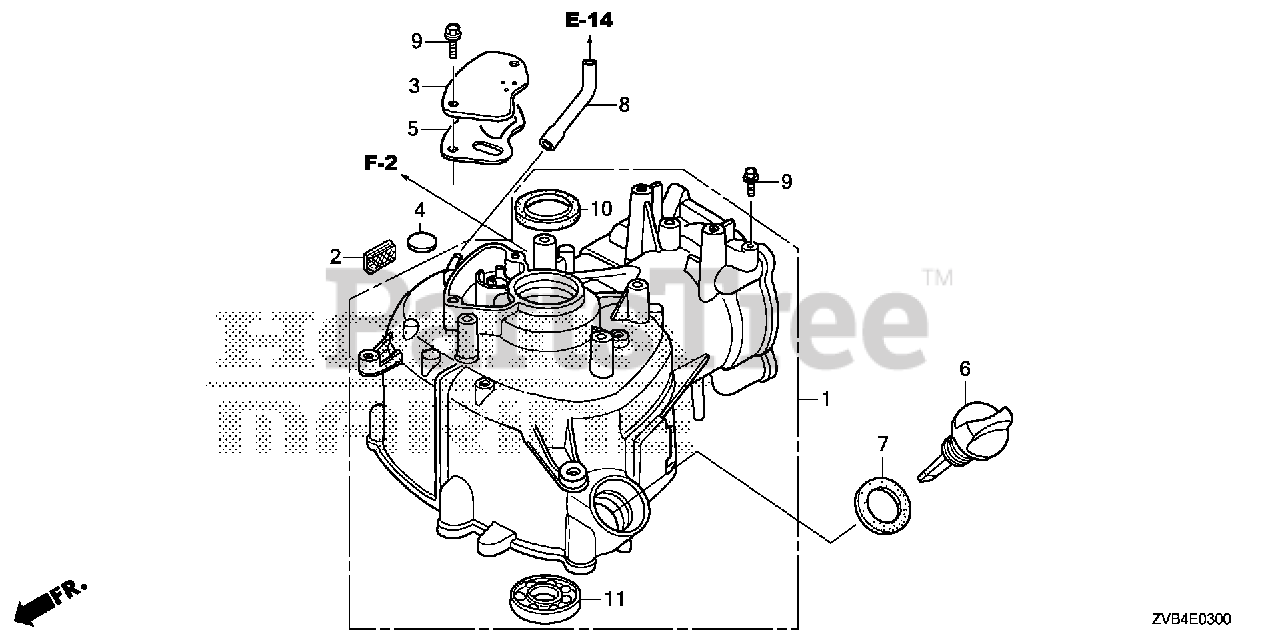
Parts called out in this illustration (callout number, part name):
1	CYLINDER ASSY. *NH8* (DARK GRAY)
2	FILTER, BREATHER
3	CAP, BREATHER CHAMBER
4	VALVE, BREATHER
5	GASKET, BREATHER CAP
6	CAP, OIL FILLER
7	GASKET, OIL FILLER CAP
8	TUBE, BREATHER
9	BOLT, FLANGE (6X12)
10	OIL SEAL (25X38X7)
10	OIL SEAL (25X38X7) (ARAI)
11	BEARING, RADIAL BALL (6205)
